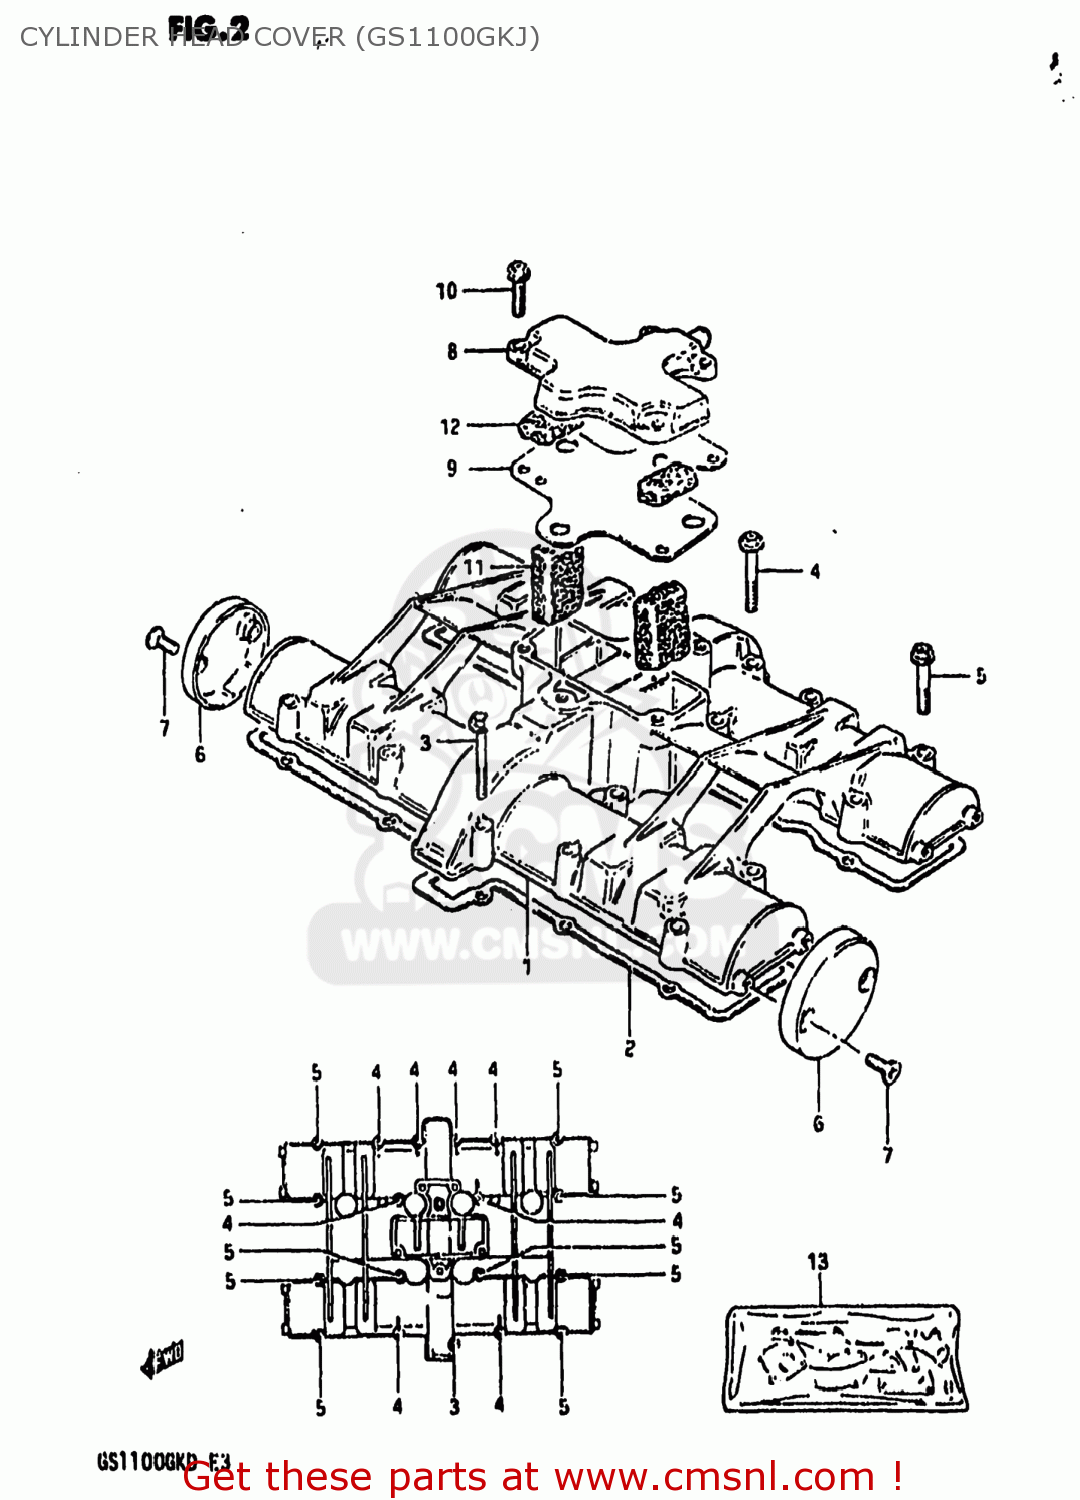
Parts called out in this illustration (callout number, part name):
1	COVER,CYLINDER HEAD
2	GASKET,CYLINDER HEAD COVER (MCA)
3	BOLT (6X45)
4	BOLT
5	BOLT
6	CAP,CYLINDER HEAD COVER
7	SCREW(5X12)
8	COVER,BREATHER
9	GASKET (MCA)
10	BOLT
11	COVER,BREATHER
12	SEPARATOR,OIL BREATHER
13	GASKET SET
